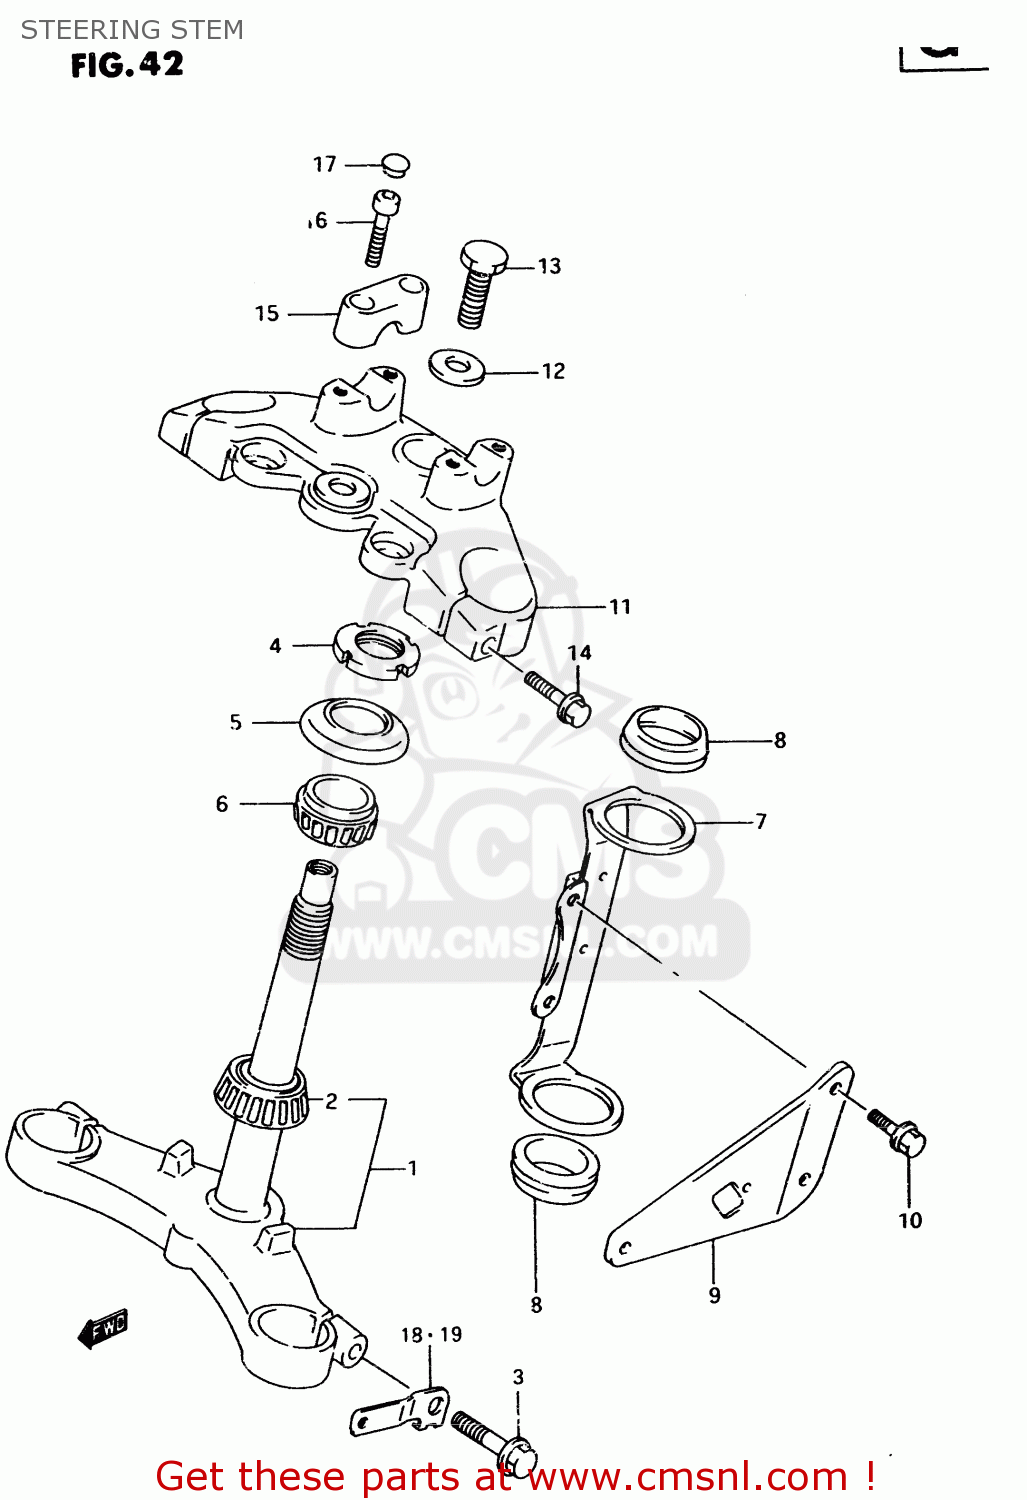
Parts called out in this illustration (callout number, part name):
1	STEM,STEERING
2	BEARING(30X55X17)
3	BOLT
4	NUT,STEERING STEM(25X44X10)
5	SEAL,STEERING UPR DUST
6	BEARING(25X47X15)
7	BRACKET,HEADLAMP,R
8	CUSHION,HEADLAMP BRACKET
9	STAY,HEADLAMP HOUSING,R
10	SCREW(6X12)
11	HEAD,STEERING STEM
12	WASHER,STEERING STEM
13	BOLT,STEERING STEM HEAD
14	BOLT
15	HOLDER,HANDLE(BLACK)
16	BOLT
17	CAP(OD:10)
18	BRACKET, LEAF REFLECTOR RH
19	BRACKET, LEAF REFLECTOR LH
